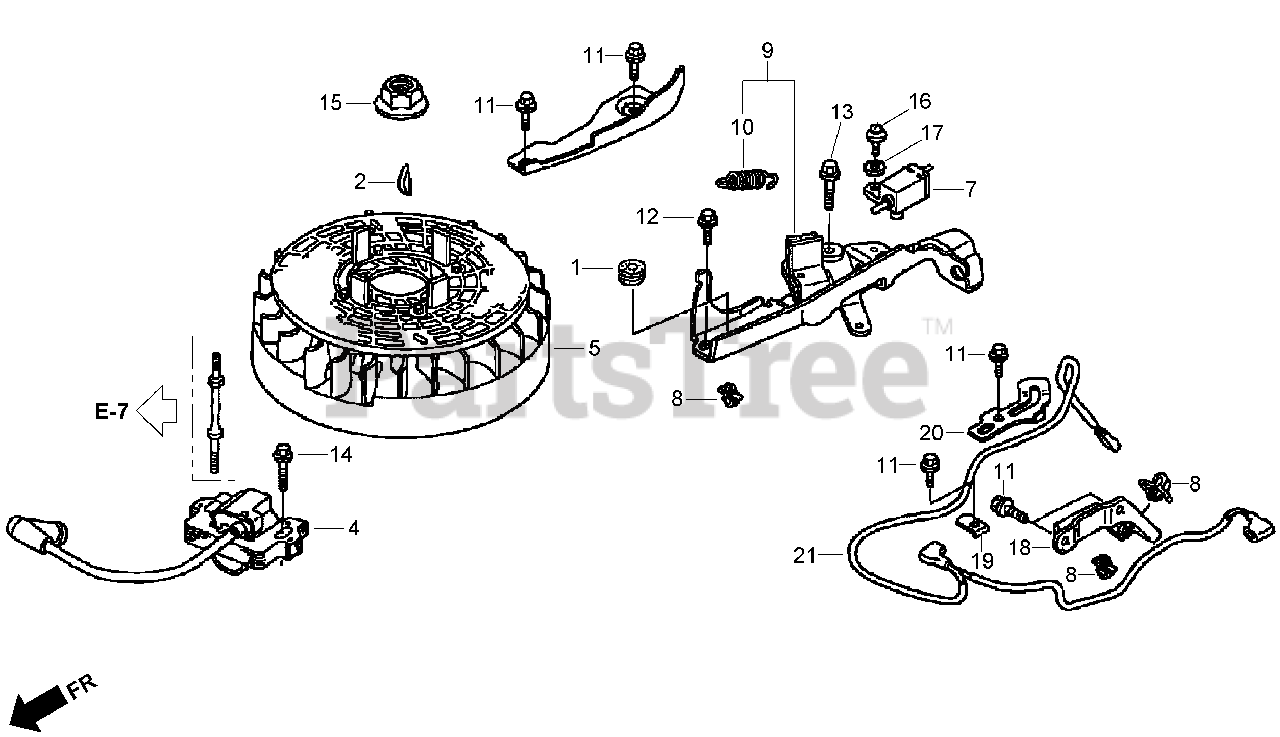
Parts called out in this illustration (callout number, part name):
1	GROMMET A-COVER, REAR (8X16X6.6)
1	GROMMET A, RR COVER (8X16X8)
2	KEY-WOODRUFF, SPECIAL (25X18)
4	IGNITION COIL ASM (PHELON) (USE FOR FLYWHEEL OF PHELON)
5	FLYWHEEL ASM (PHELON) (USE FOR IGNITION COIL OF PHELON)
7	ENGINE STOP SWITCH ASM (N C)
8	HOLDER-WIRE (FASTEX)
8	CLIP A-CABLE (3.8MM BLACK) (NIFCO)
9	BRAKE ASM
10	SPRING-LEVER, BRAKE
11	BOLT-FLANGE (6X12) (C T200)
12	BOLT-FLANGE (6X14) (C T200)
13	BOLT-FLANGE (6X23) (C T200)
14	BOLT-FLANGE (6X20) (C T200)
15	NUT-FLANGE (14MM)
16	SCREW-WASHER (4X12)
17	WASHER-PLAIN (4MM)
18	CLAMP-WIRE, STOP SWITCH
19	CLAMP-WIRE, STOP SWITCH
20	CLAMP-WIRE
21	WIRE-SWITCH, STOP
